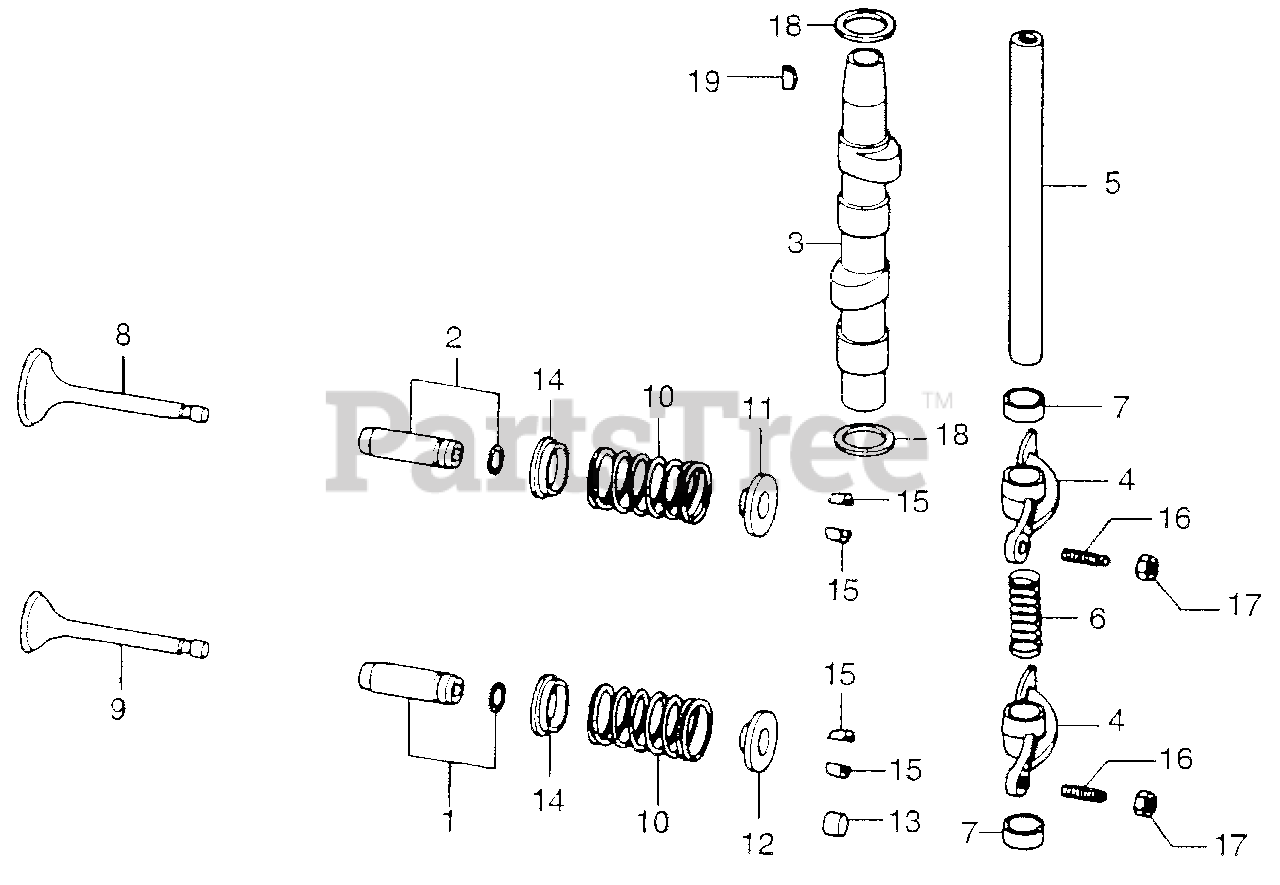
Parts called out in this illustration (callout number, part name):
1	GUIDE, VALVE
2	GUIDE, VALVE (NOT AVAILABLE)
4	ARM, VALVE ROCKER (NOT AVAILABLE)
5	SHAFT, VALVE ROCKER ARM
6	SPRING, ROCKER ARM
7	COLLAR, ROCKER ARM (NOT AVAILABLE)
8	VALVE, IN.
9	VALVE, EX. (NOT AVAILABLE)
10	SPRING, VALVE
11	RETAINER, VALVE SPRING (NOT AVAILABLE)
14	SEAT, VALVE SPRING
15	COTTER, VALVE
16	SCREW, TAPPET ADJ. (NOT AVAILABLE)
17	NUT, TAPPET ADJ.
18	WASHER, THRUST (16MM)
19	KEY, WOODRUFF (16X12)
